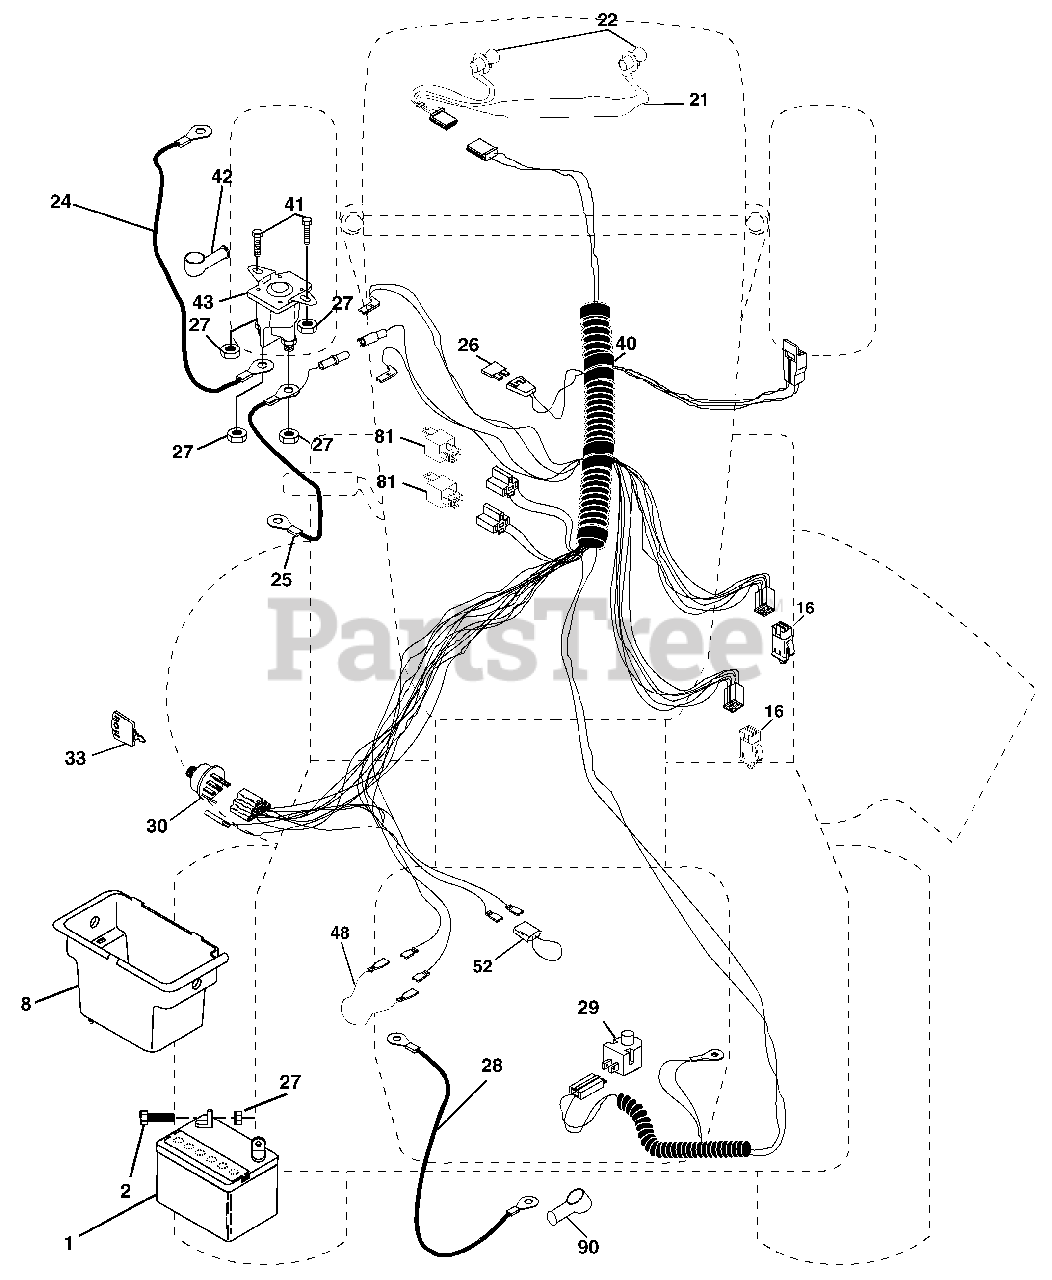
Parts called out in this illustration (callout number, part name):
1	Battery 12 Volt 28 AMP
2	Bolt Hex Hd 1/420unc X 3/4
8	Battery Box
16	Switch Interlock Push In
21	Harness Asm Light W/4152j
22	Bulb Light #1156
24	Cable Battery 6 Ga 11" red
25	Cable Battery 6 Ga 44" red w/16 wire
26	Fuse 20 AMP
27	Nut Keps Hex 1/420 Unc
28	Cable Ground 6 Ga 12" black
29	Switch Plunger Nc Gray
30	Switch Ign
40	Harness Ign.
41	Bolt Blk Fin Hex 1/4 20 x 1/2
42	Cover Terminal Red
43	Solenoid
48	Adapter Ammeter
52	Protection Wire Loop
81	Relay Asm.
90	Cover Terminal
